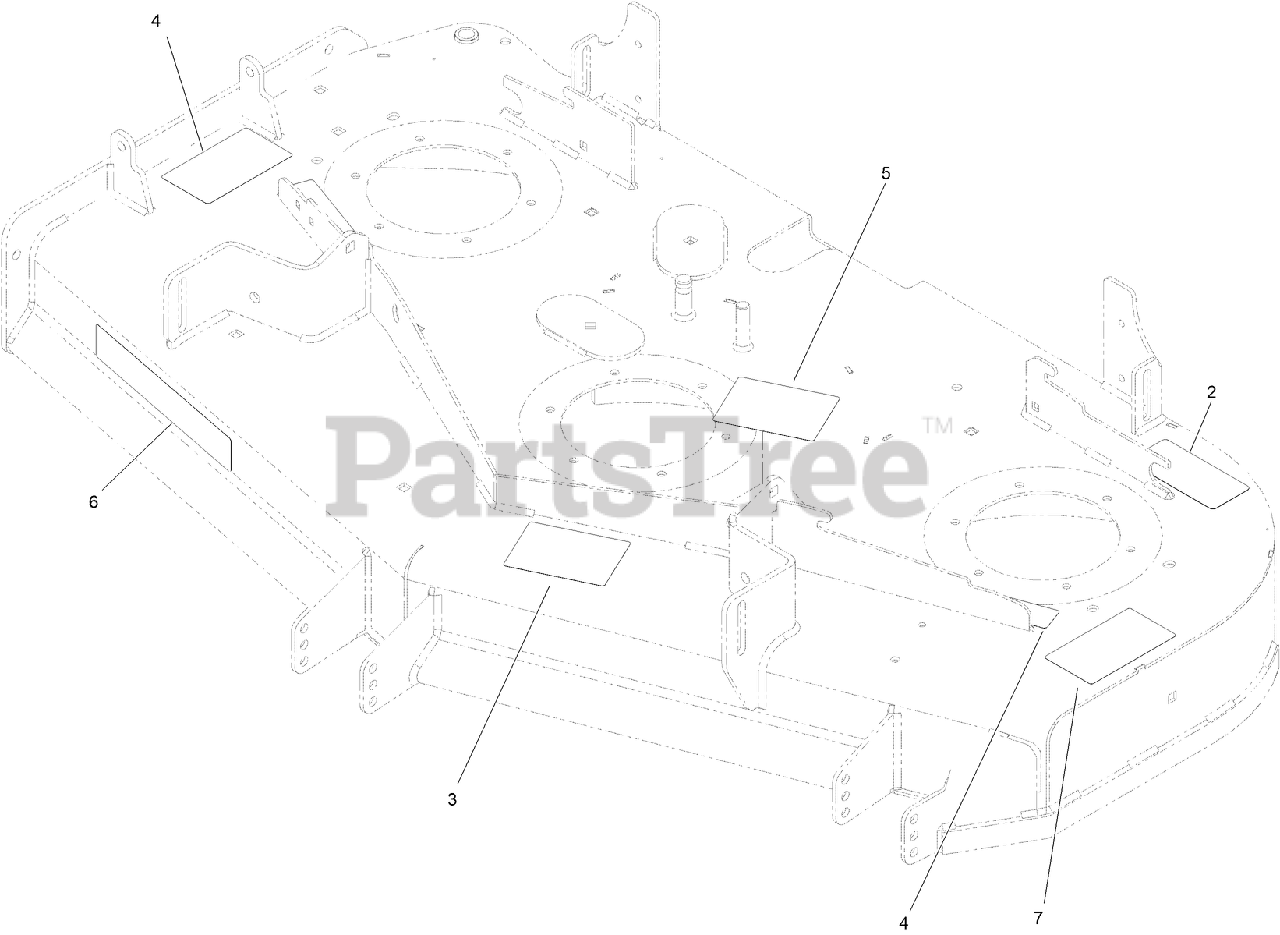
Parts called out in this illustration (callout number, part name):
2	DECAL-TORQUE, BLADE BOLT
3	DECAL-SCALP, ANTI
4	DECAL-MISSING, COVER
5	DECAL-ROUTING, BELT
7	DECAL-DANGER
